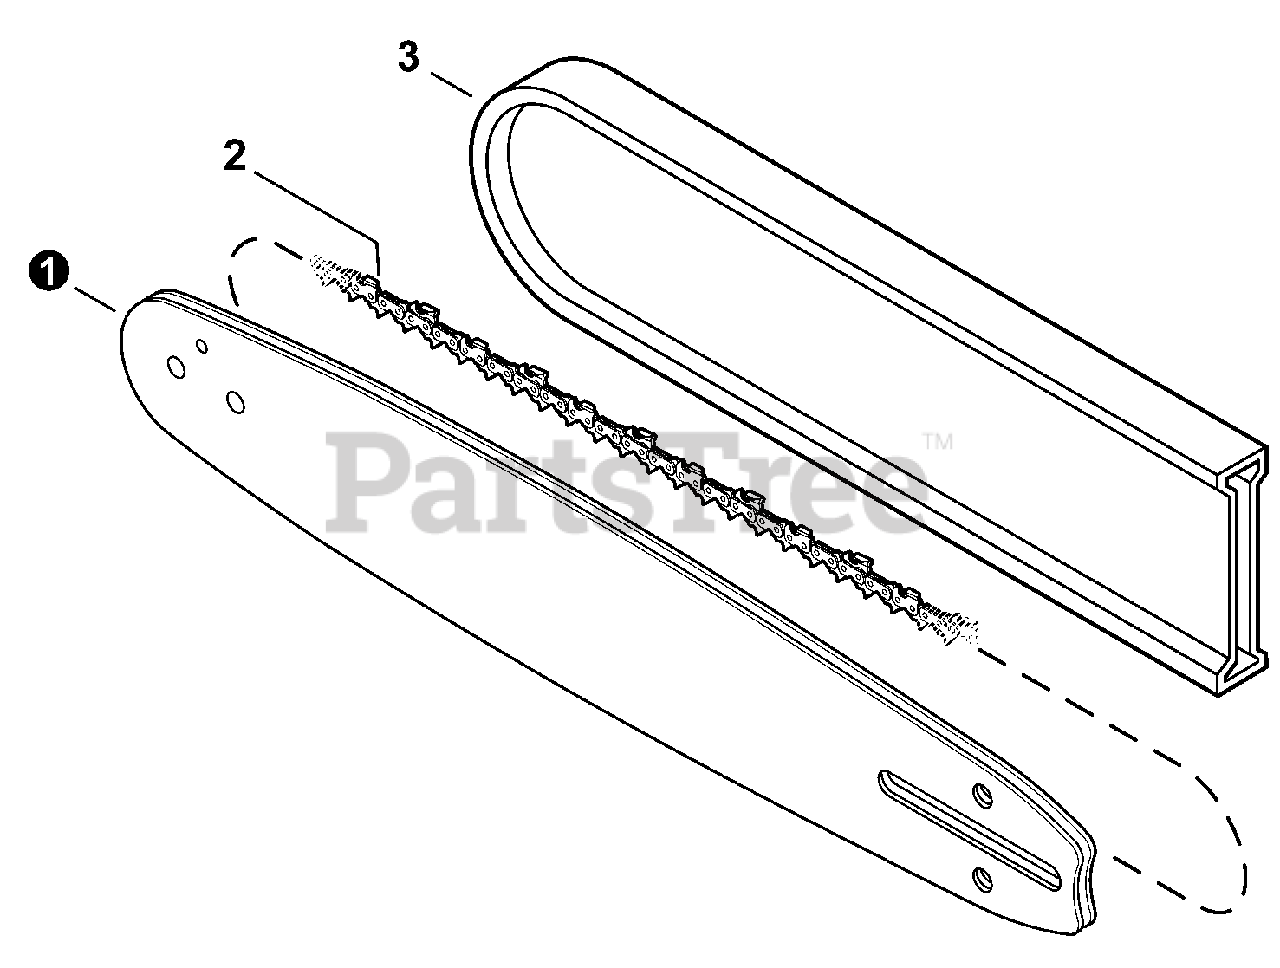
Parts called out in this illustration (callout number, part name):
1	GUIDE BAR, 16" 0.325
1	GUIDE BAR, 18" 0.325
1	GUIDE BAR, 20" 0.325
2	SAW CHAIN 16"
2	SAW CHAIN 18"
2	SAW CHAIN 20"
3	SCABBARD 12"-20"
